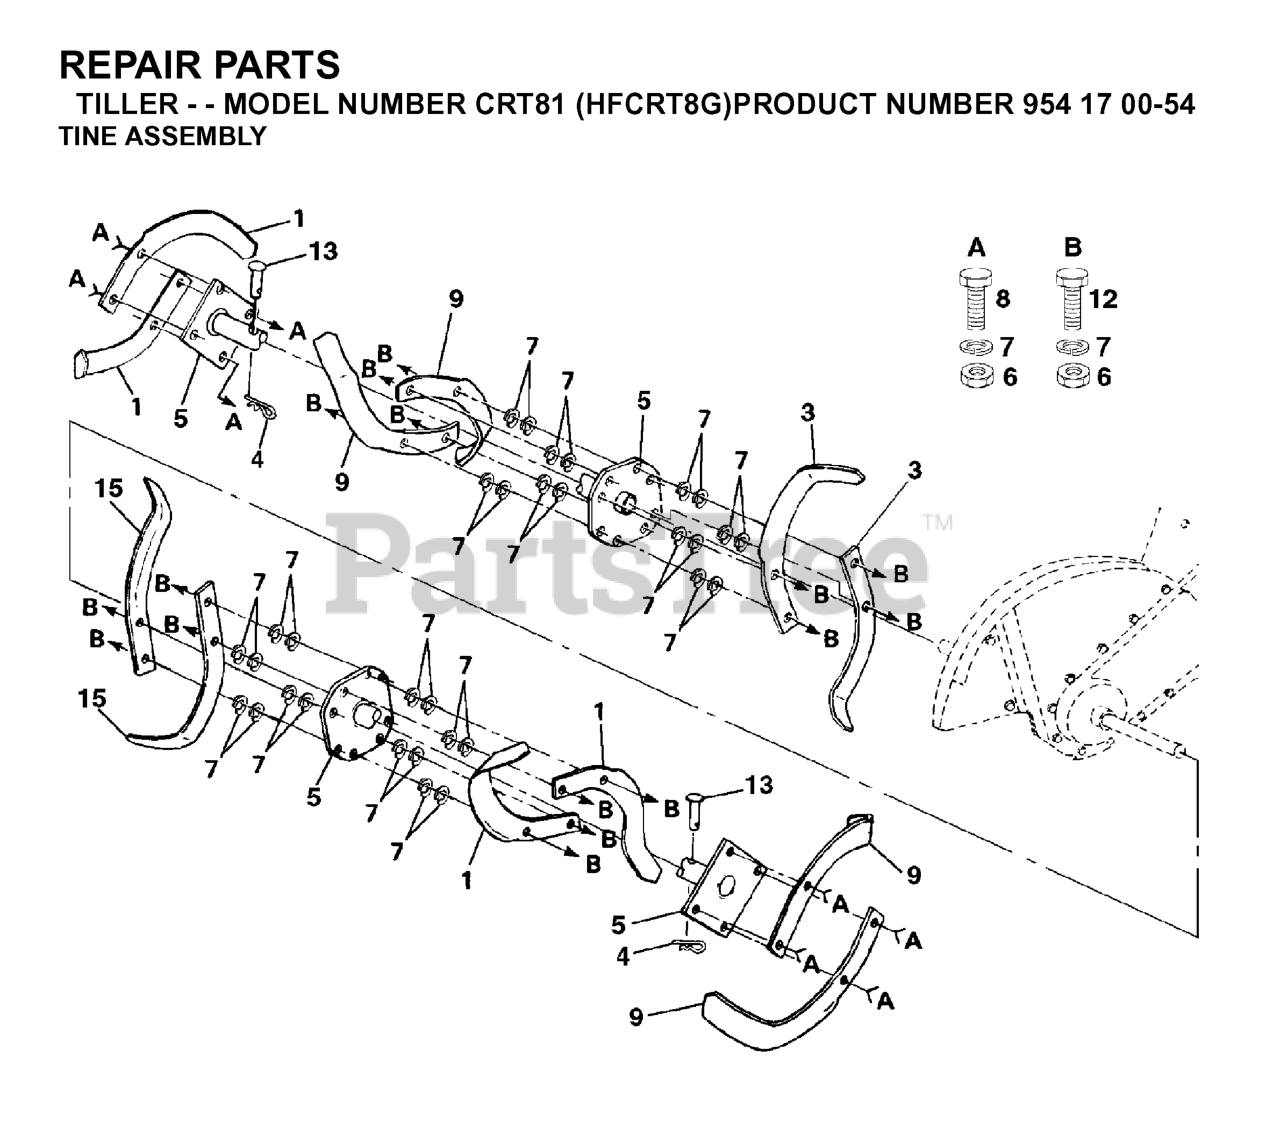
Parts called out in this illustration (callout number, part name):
1	TINE, LH 14"
3	TINE.LH.14".CRT
4	SPRING RETAINER
5	DNO HUB ASMBLY
6	NUT
7	WASHER, LOCK 3/8
8	BOLT.HEX.001X20.37-24X1.ZINC
9	TINE, RH 14"
12	BOLT.3/8-24X1-1/2
15	TINE.RH.14".CRT
